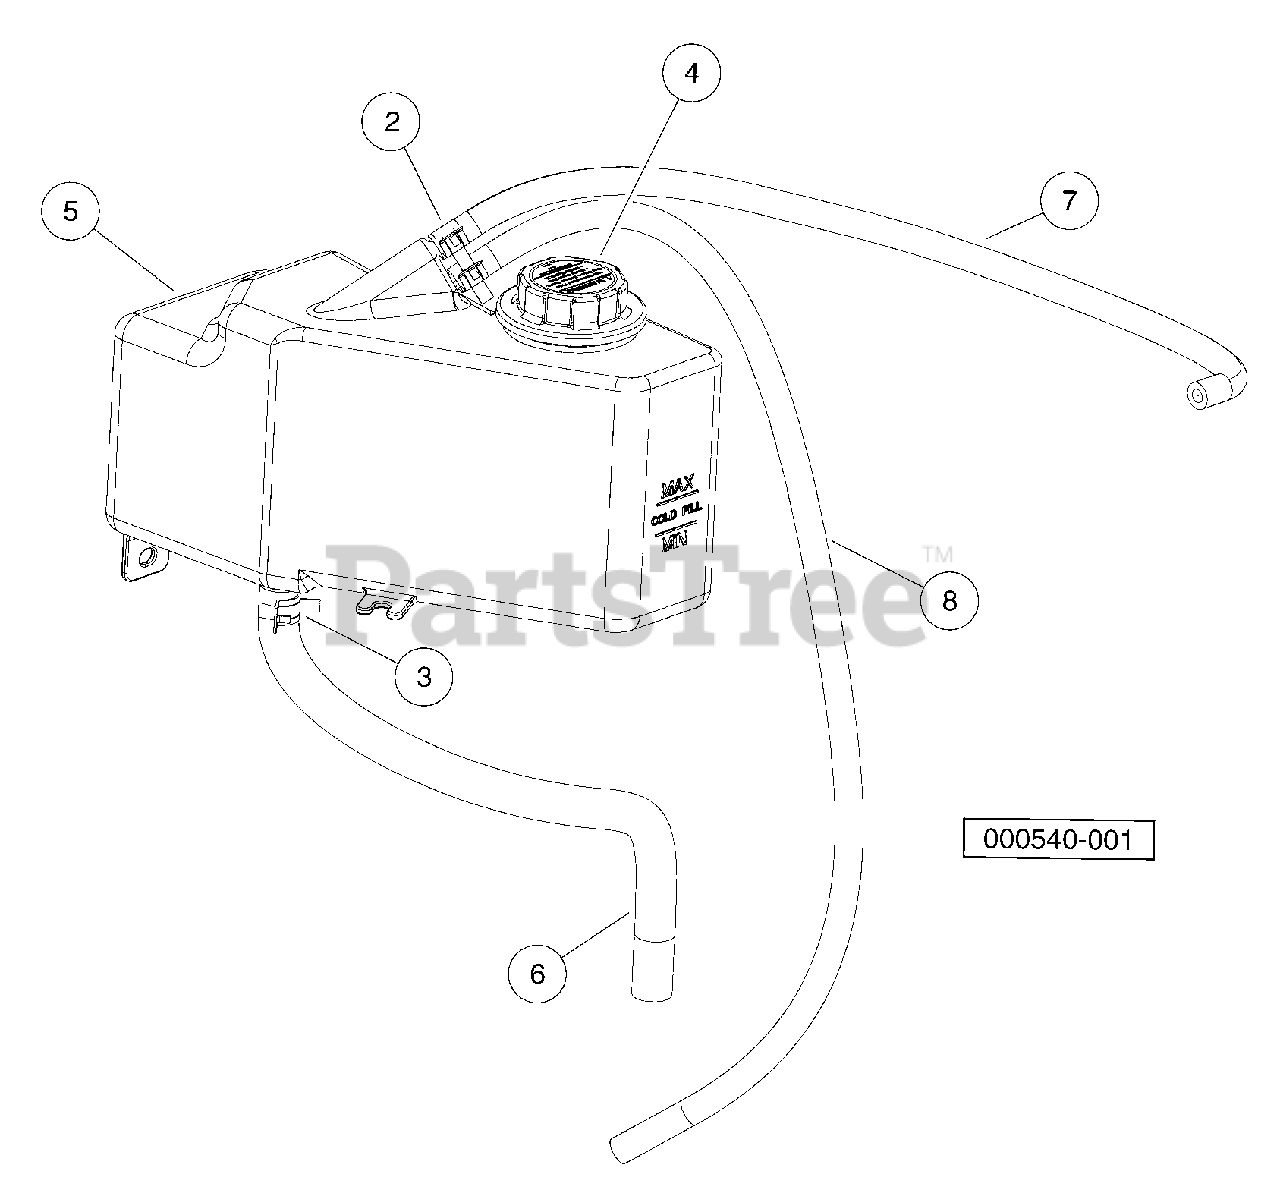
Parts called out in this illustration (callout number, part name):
1	Asm, Coolant Bottle
2	Clamp, Hose, CTB 15mm
3	Clamp, Hose, CTB 22mm
4	Cap, Radiator
5	Bottle, Coolant
6	Hose, Cut, 5/8, 445
7	Hose, Cut, Coolant, 700
8	Hose, Cut, Coolant, 1100
